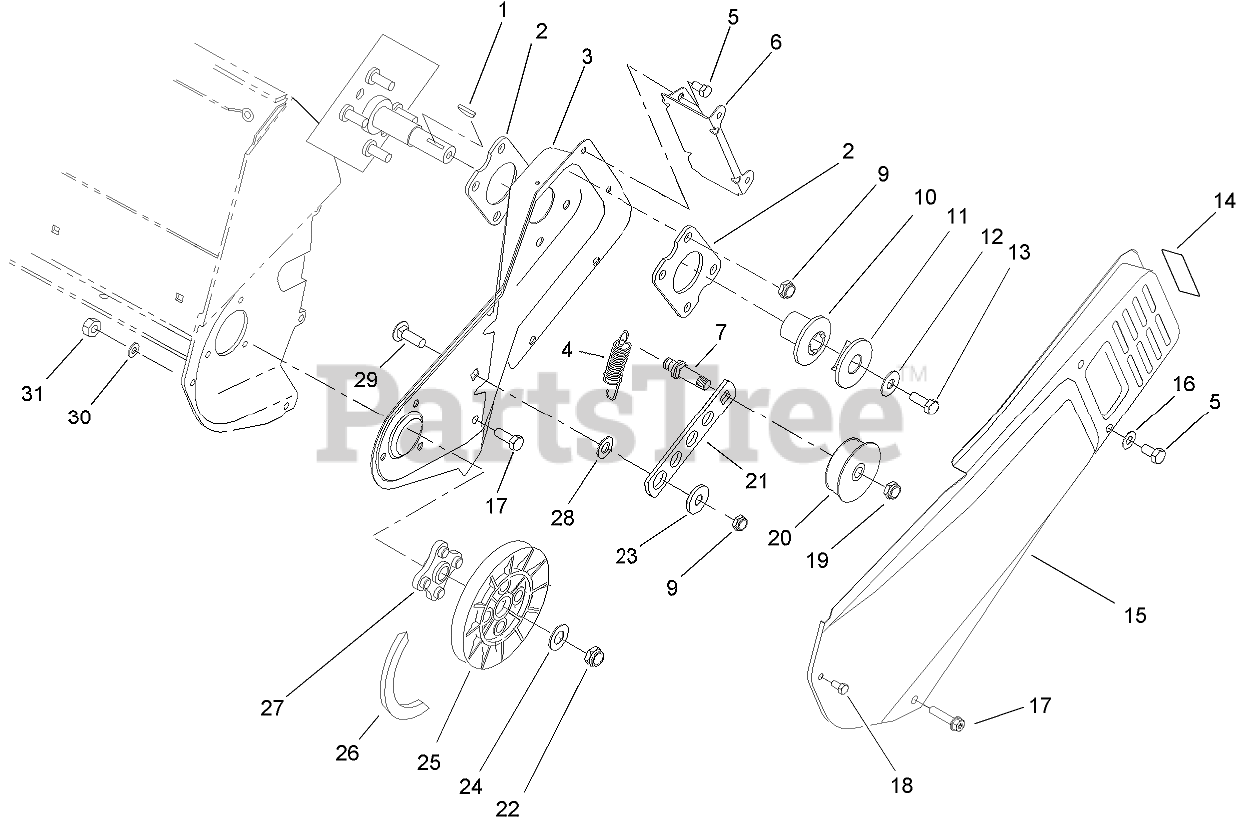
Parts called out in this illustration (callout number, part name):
1	KEY-WOODRUFF
2	PLATE-ENGINE
3	SIDEPLATE-LH
4	SPRING-EXTENSION
5	SCREW-HWH
6	BRACKET-COVER, BELT
7	PIN-IDLER
9	NUT-LOCK, NI
10	Hub-HALF SHEAVE
11	CAP-HALF SHEAVE
12	WASHER-FLAT
13	SCREW-HH
14	DECAL-WARNING
15	COVER-BELT
16	WASHER-FLAT
17	SCREW-PLASTIC
19	NUT-LOCK, NI
20	PULLEY-IDLER
21	ARM-IDLER
22	NUT-LOCK, NI
23	BUSHING-IDLER
24	WASHER-FLAT
25	PULLEY-DRIVEN
26	V-BELT
28	WASHER
29	SCREW-CARR
30	WASHER-FLAT
31	NUT-LOCK, NI
